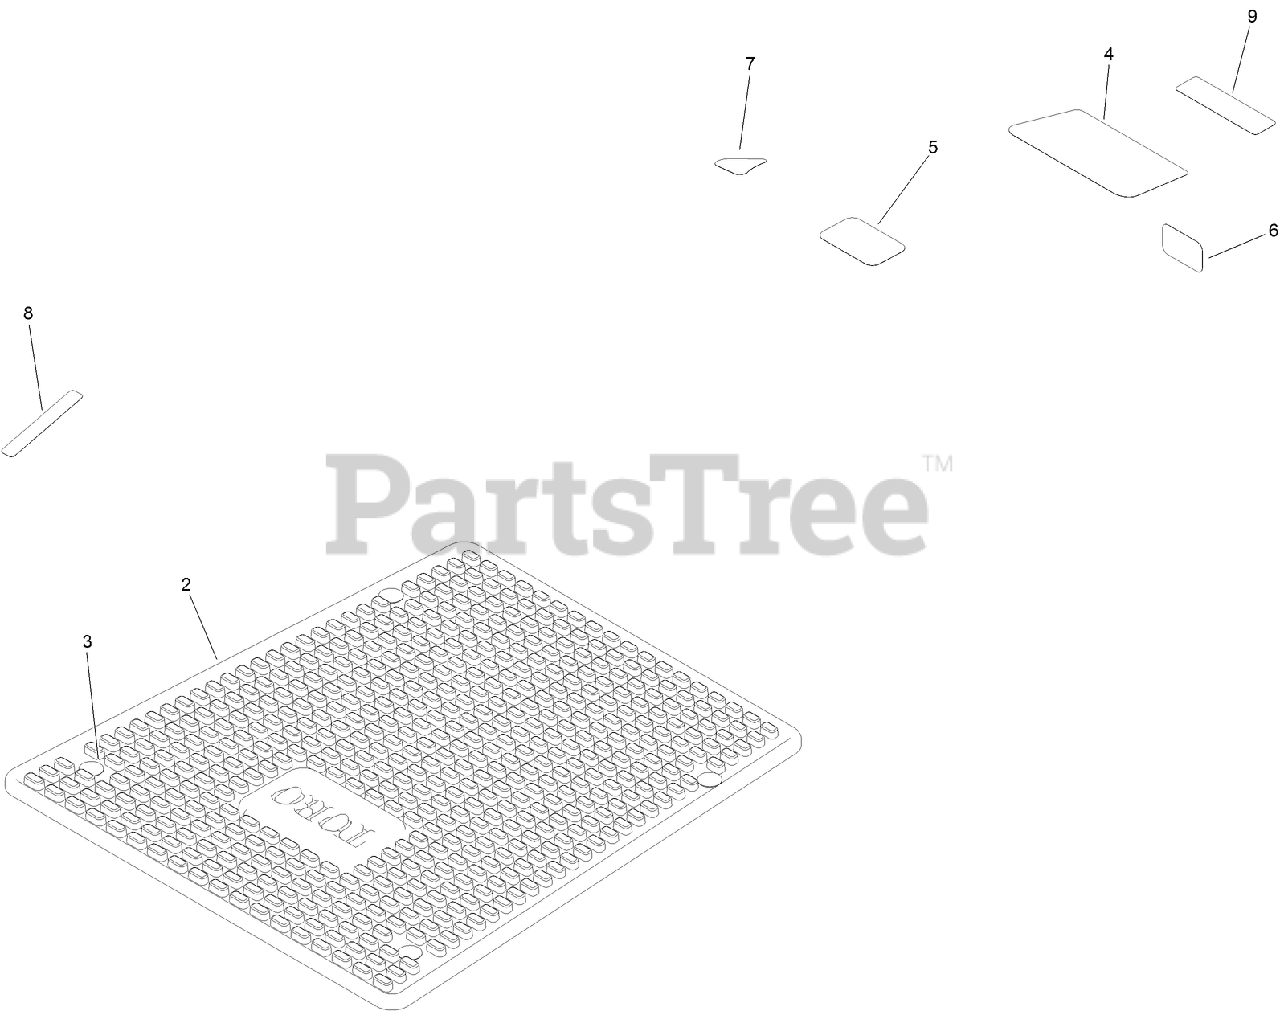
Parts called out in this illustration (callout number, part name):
2	MAT-FLOOR
3	PLUG-PLASTIC
4	DECAL-ENGINE
6	PLACARD-INTAKE
7	DECAL-DRAIN, OIL
8	DECAL-SHUTDOWN
9	DECAL-BUCKET
